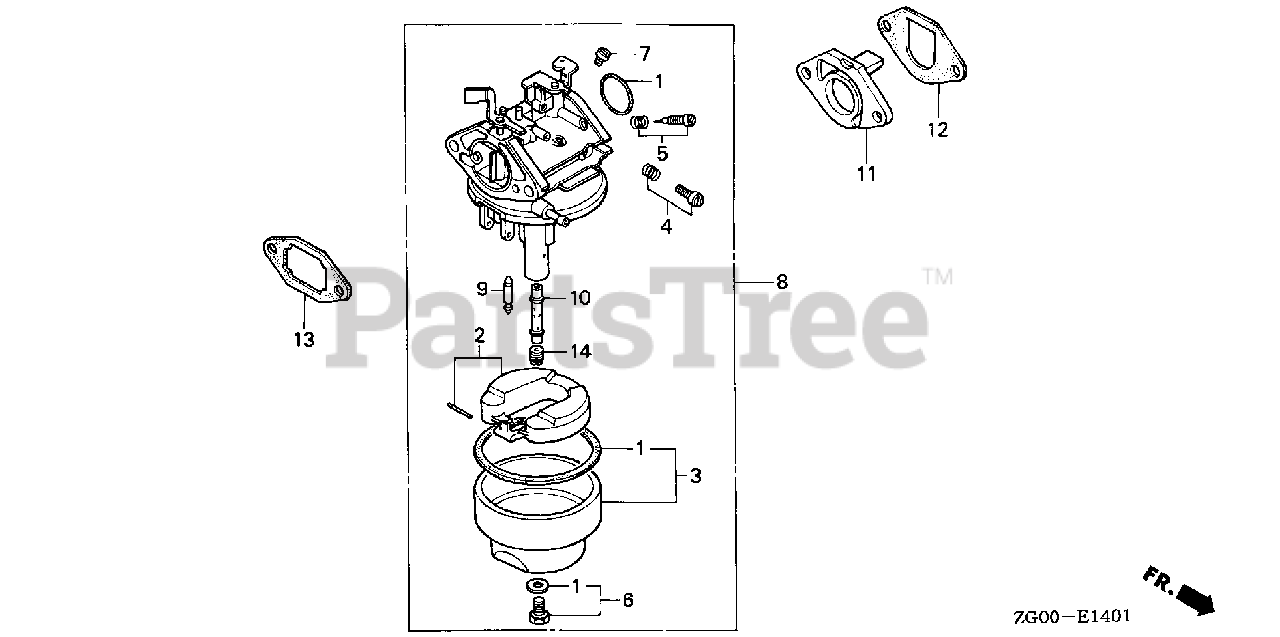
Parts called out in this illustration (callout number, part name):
1	GASKET SET
3	CHAMBER SET, FLOAT
4	SCREW SET A
5	SCREW SET A
6	SCREW SET
7	SCREW, PLUG
8	CARBURETOR ASSY.
9	VALVE, FLOAT
10	NOZZLE, MAIN
11	INSULATOR, CARBURETOR
12	GASKET, INSULATOR
13	GASKET, AIR CLEANER
14	JET, MAIN (#45)
14	JET, MAIN (#48)
14	JET, MAIN (#50)
14	JET, MAIN (#52)
14	JET, MAIN (#55)
